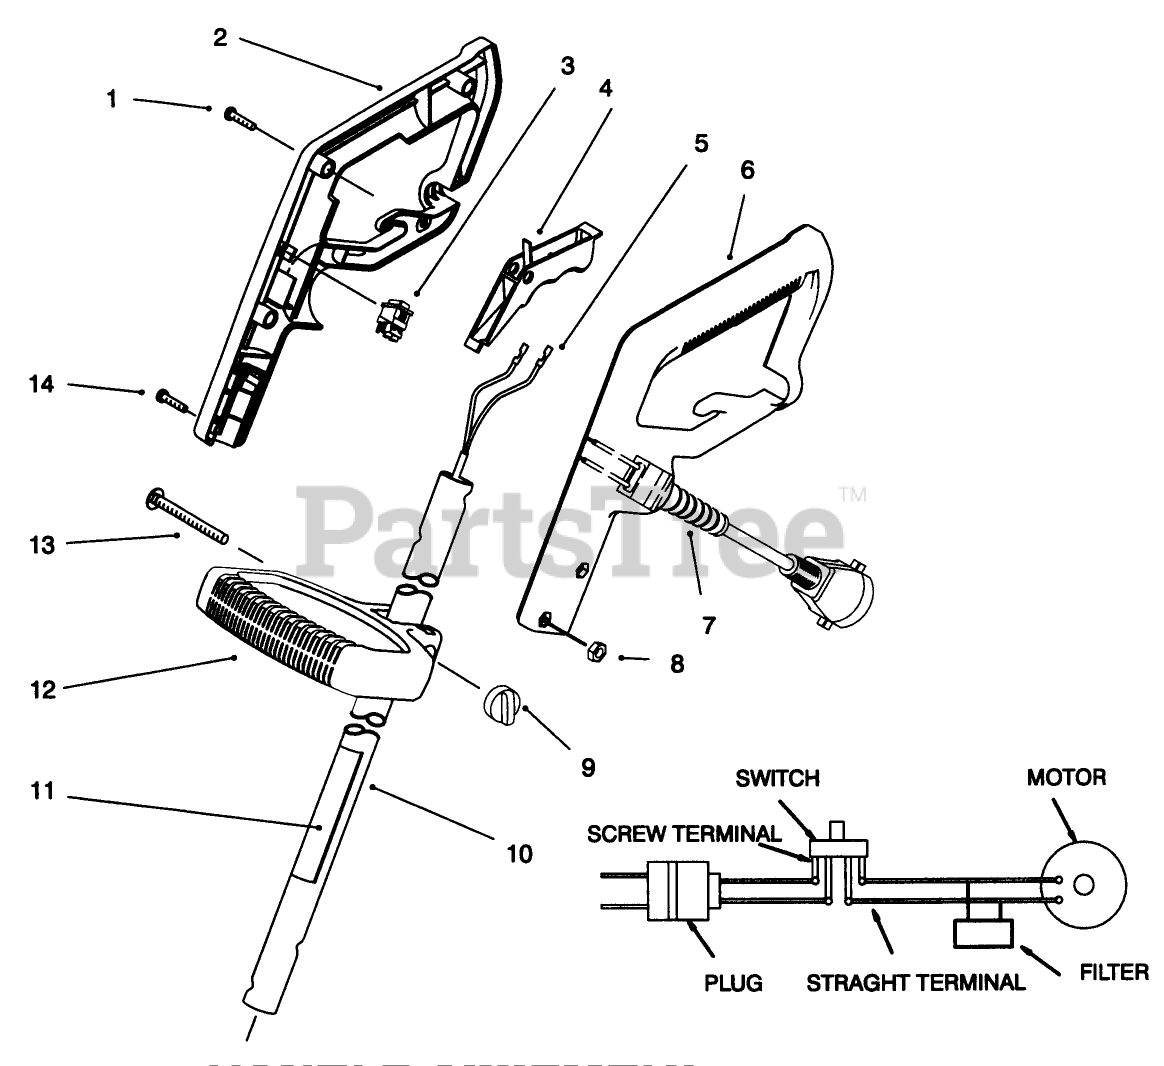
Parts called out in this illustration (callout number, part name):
1	SCREW-PPH
2	HAND GRIP RH
3	SWITCH - 230V
4	TRIGGER
5	HARNESS - WIRE
6	HAND GRIP LH
7	CORD - POWER
8	NUT-HEX
9	KNOB, VFL/FFL
10	Tube Assembly (Incl. Ref. #11)
11	Decal-Safety
12	MID HANDLE
13	SCREW-CARR
14	SCREW-PPH
